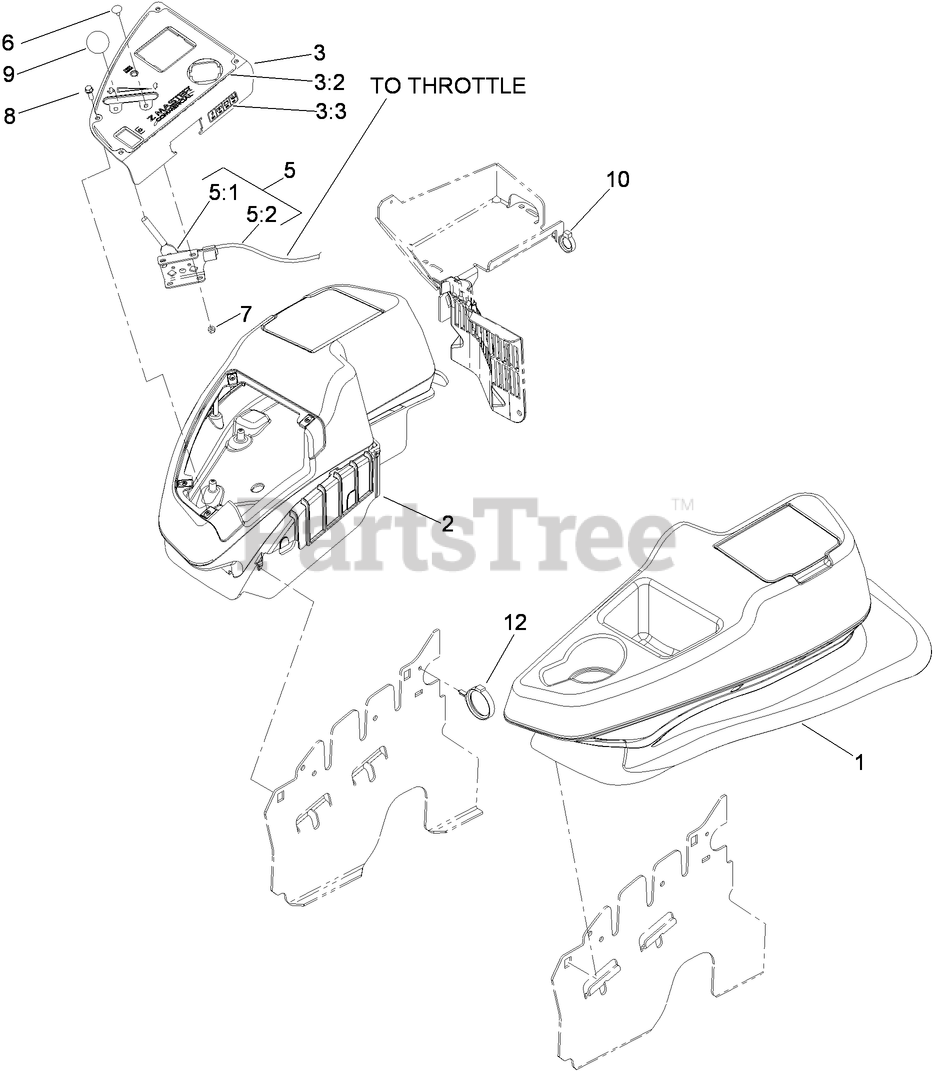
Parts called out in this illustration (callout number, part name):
1	LH CONSOLE ASM
2	RH CONSOLE ASM
3	CONTROL PANEL ASM
3:2	DECAL-PANEL, CONTROL
3:3	DECAL-FUSES
5	THROTTLE CONTROL ASM
5:1	LEVER-THROTTLE
5:2	CABLE-THROTTLE
6	BOLT-CARR
7	NUT-LOCK, NI
8	SCREW-HWH
9	KNOB-BALL
10	CLAMP-HOSE
12	CLAMP-HARNESS
